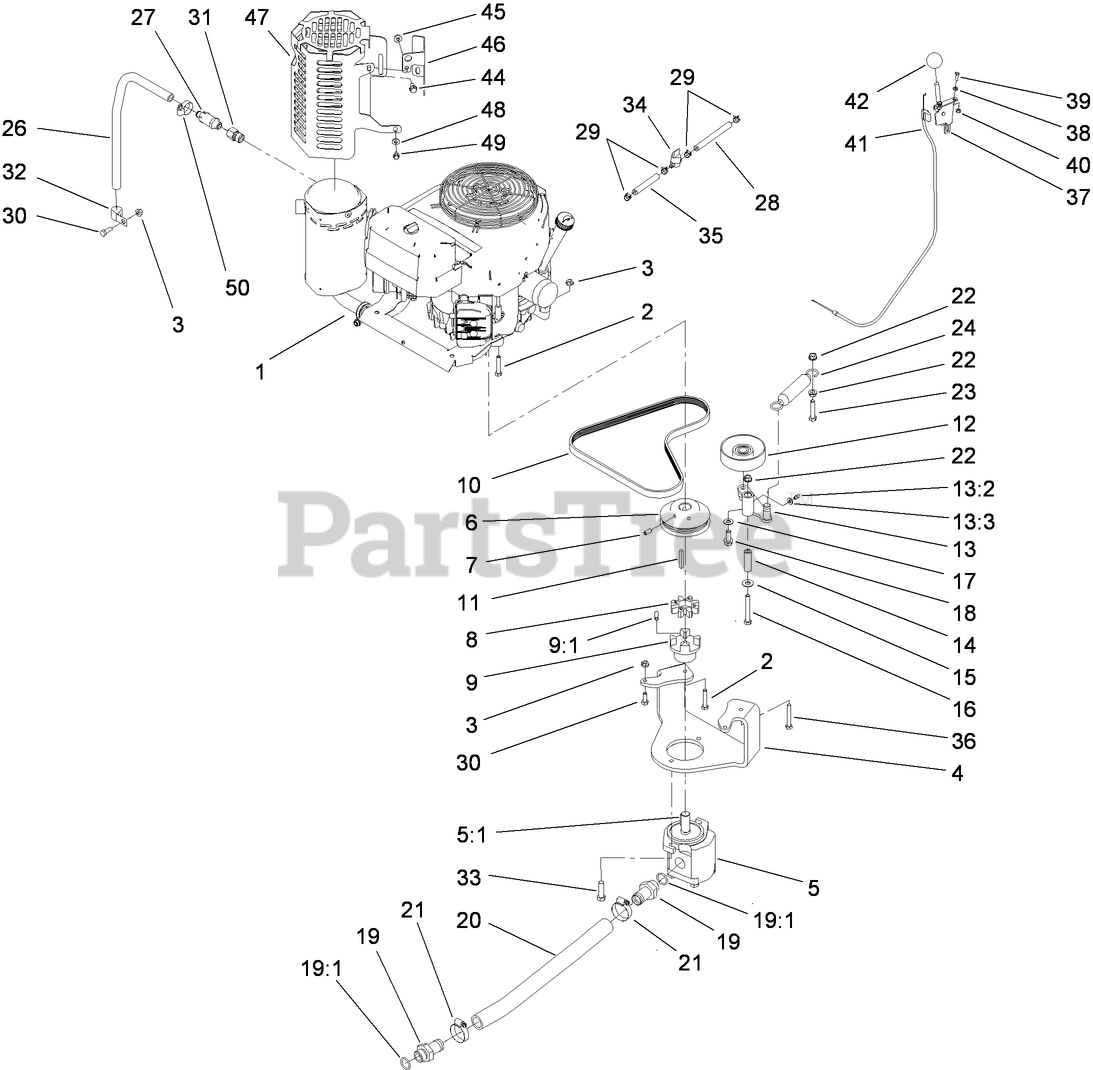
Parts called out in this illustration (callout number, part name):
1	ENGINE ASM
2	SCREW-HH
3	NUT-HF
4	MOUNT-PUMP
5	GEAR PUMP ASM
5:1	KEY-SQUARE
6	PULLEY-ENGINE
7	SCREW-SET, HSH
8	COUPLER-SPIDER
9	COUPLER-FLEX
9:1	SCREW-SET
10	BELT-V
11	KEY-SQUARE
12	PULLEY-IDLER
13	IDLER ARM ASM
13:2	FITTING-GREASE
13:3	WASHER-FLAT
14	BUSHING-IDLER
15	WASHER-FLAT
16	SCREW-HH
17	WASHER-FLAT
18	SCREW-HHF
19	FITTING
19:1	O-RING
20	HOSE-SUCTION
22	NUT-HHF, WHIZ
23	SCREW-HH
24	Spring-Extension
26	HOSE-VENT
27	VALVE-DRAIN, OIL
28	HOSE-FUEL
29	CLAMP-HOSE
30	SCREW-HH
31	Adapter
32	CLAMP-R
33	SCREW-HH
34	VALVE-FUEL
35	HOSE-FUEL
36	SCREW-HH
37	LEVER-CONTROL
38	WASHER-FLAT
40	NUT-LOCK, NI
41	CABLE-CONTROL
44	SCREW-HHF
45	NUT-HF
46	BRACKET-GUARD, MUFFLER
47	MUFFLER SHIELD ASM
48	WASHER-FLAT
49	SCREW-HHF
50	CLAMP-HOSE
